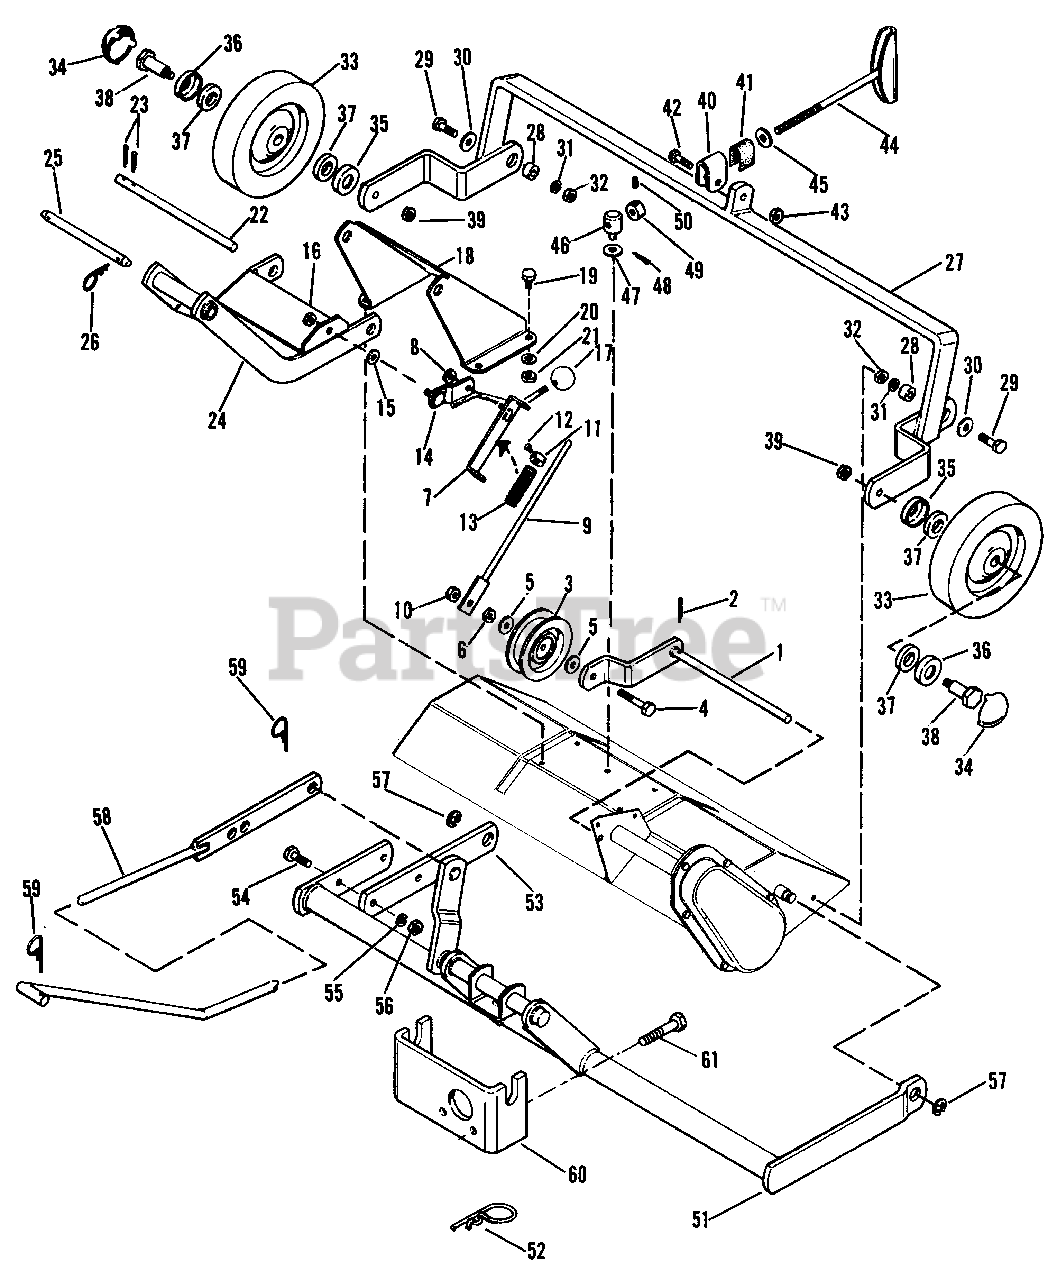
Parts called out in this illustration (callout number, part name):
1	Idler Arm Assembly
2	Cotter Pin, 1/8 x 1" lg.
3	Idler Pulley
4	Hex Capscrew, 3/8"-16 x 1-3/4" lg.
5	Plain Washer, 5/16"
6	Hex Nut, Full, 3/8"-16
7	Rod Guide Assembly
8	Hex Nut Full Lock, Jam, 5/16"-18
9	Clutch Rod Assembly
10	Hex Nut, Full, 3/8"-16
12	Set Screw, Sq. Hd., Clip Pt. 1/4"-20 x 3/8"
14	Clutch Lever Assembly
15	Special Washer
16	Hex Nut, Full, 5/16"-18
18	Arm Support
19	Hex Capscrew, 5/16"-18 x 5/8" lg.
20	Lock Washer, 5/16"
21	Hex Nut, Full, 5/16"-18
22	Pivot Pin
23	Cotter Pin, 1/8" x 1" lg.
24	Link Assembly
26	Spring Clip
27	Frame Assembly
29	Hex Capscrew, 3/8"-16 x 1" lg.
30	Plain Washer. 5/16"
31	Lock Washer 3/8"
32	Hex Nut, Full, 3/8"-16
35	Seal Housing
36	Seal Housing
37	Wheel &al
38	Wheel Bolt
39	Hex Nut, Lock, Jam 3/8"-16
42	Hex Capscrew, 5/16"-18 x 1-1/4" lg.
43	Hex Nut Full, Lock, 5/16"-8
44	Adjusting Screw Assembly
45	Plain Washer, 3/8"
47	Plain Washer, 5/16"
48	Cotter Pin, 3/32" x 3/4" lg.
49	Set Collar
50	Soc. Hd. Set Screw, Hollow Pt., 1/4"-20 x 5/16" lg.
51	Hitch Assembly
53	R.H. Pivot Bar
54	Hex Capscrew, 5/16"-18 x 1" lg.
55	Lock Washer, 5/16"
56	Hex Nut, Full, 5/16"-18
57	Retaining Ring
58	Lift Rod Assy.
59	Spring Clip
60	Attachment Hitch
61	Hex Capscrew, 3/8"-16 x 1-1/4" lg.
